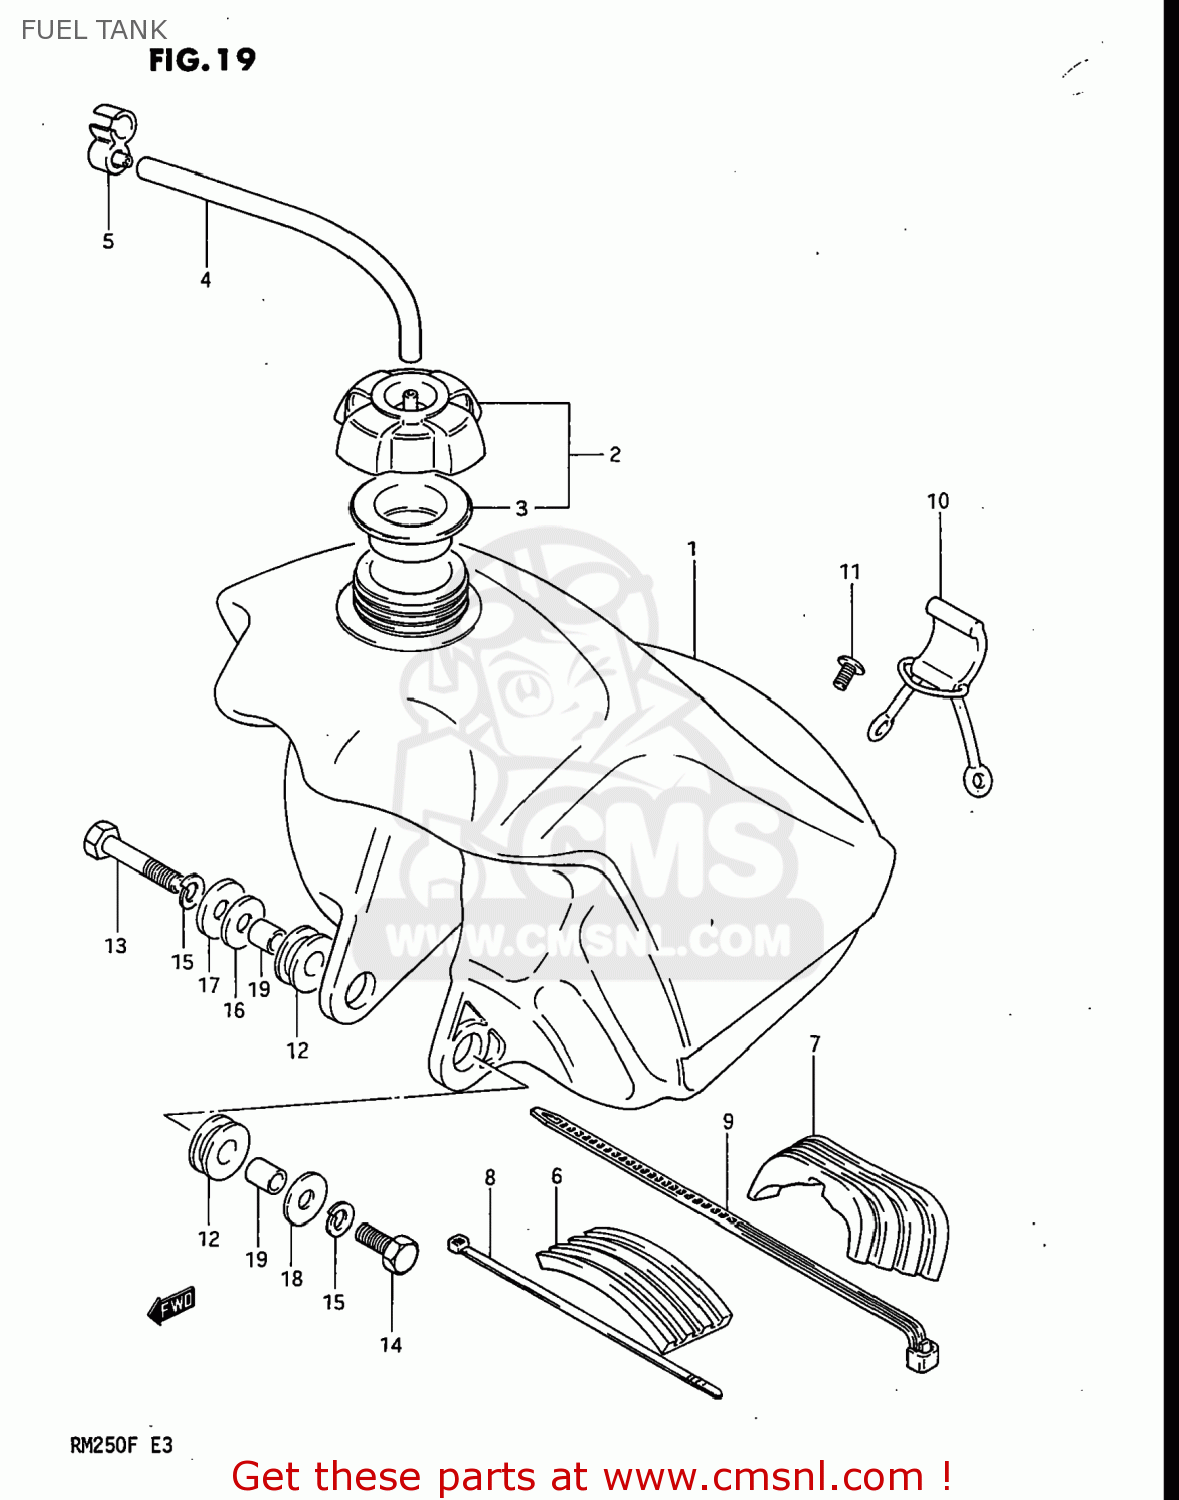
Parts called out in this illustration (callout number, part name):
1	TANK ASSEMBLY,FUEL
2	CAP SET,FUEL TANK
3	GASKET,FUEL TANK CAP (NAS)
4	HOSE
5	CLAMP,BREATHER HOSE
6	CUSHION,FUEL TANK UPR FR
7	CUSHION,FUEL TANK
8	CLAMP
9	CLAMP(L:250)
10	BAND,FUEL TANK RR
11	SCREW (6X15)
12	CUSHION
13	BOLT 8X50
14	BOLT
15	LOCK WASHER
16	WASHER
17	WASHER(8.5X26X1.2)
18	WASHER
19	SPACER (8.8X12X13.5)
